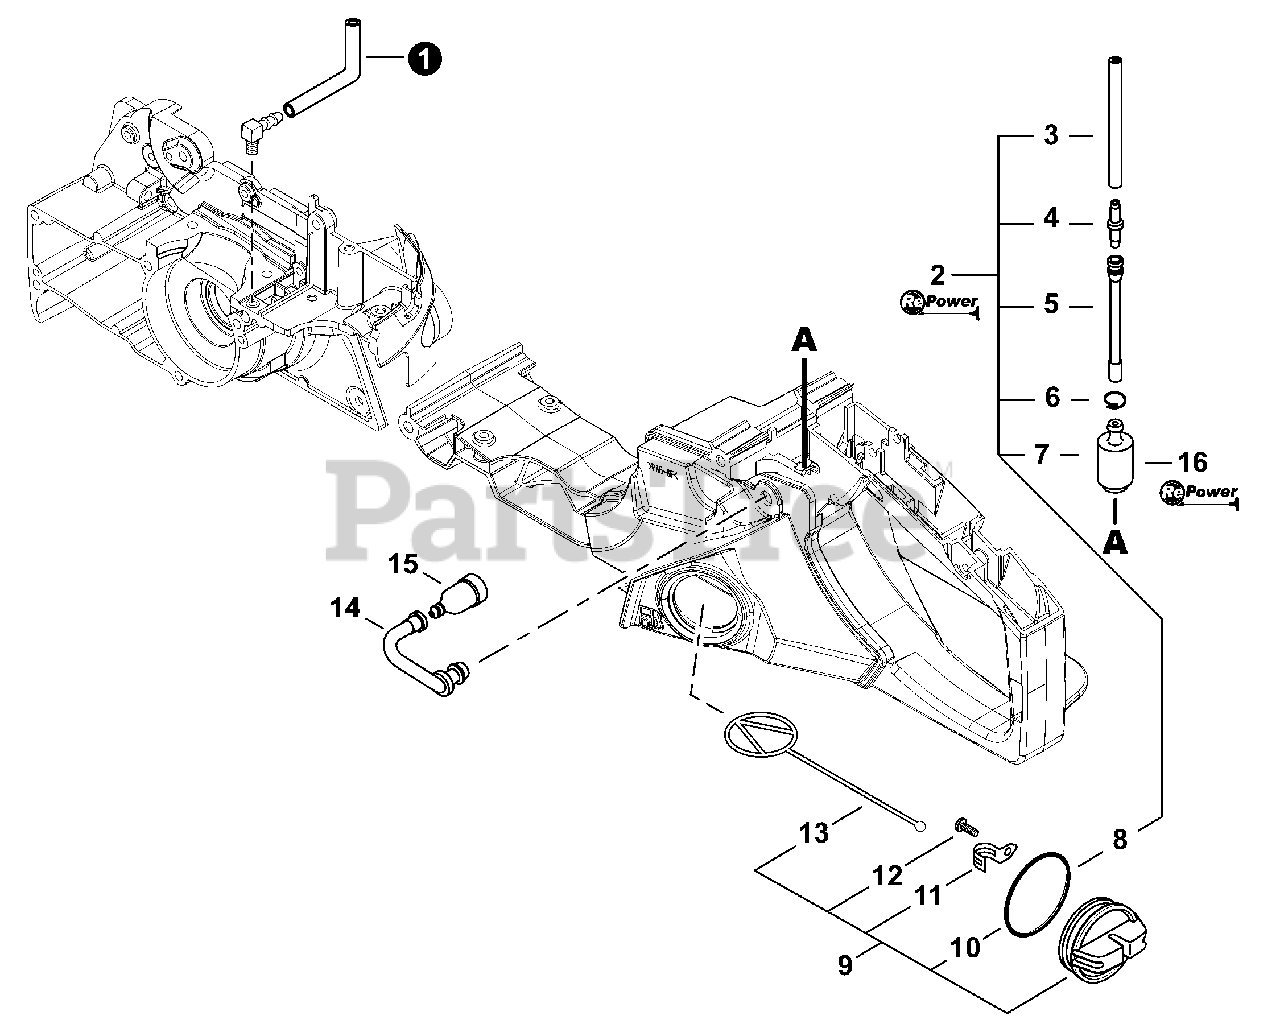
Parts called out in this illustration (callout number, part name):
1	PIPE, PULSE
2	PIPE, FUEL
3	CLIP Ø6
4	FILTER, FUEL
5	CAP ASSY, FUEL
6	O-RING 29
7	RETAINER, CONNECTOR
8	SCREW, TAPPING 3×8
9	CONNECTOR, CAP L= 60mm
10	PIPE, FUEL VENT
11	VENT ASSY
12	TUNE-UP KIT - REPOWER
